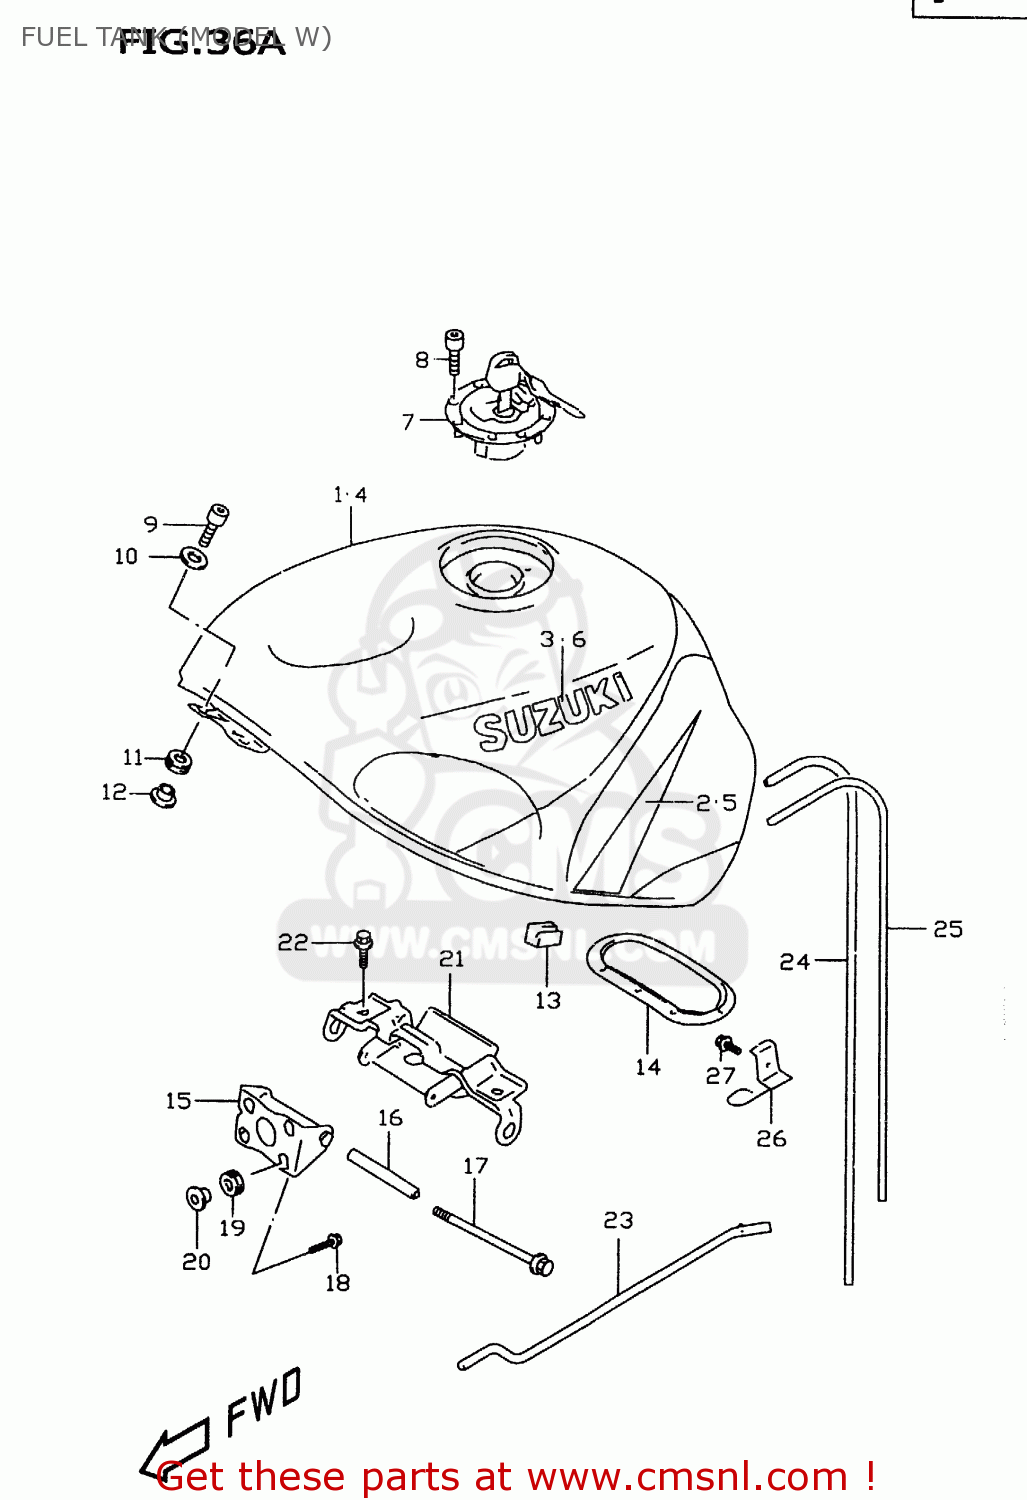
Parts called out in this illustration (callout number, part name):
1	TANK ASSEMBLY,FUEL
2	TAPE SET,FUEL TANK
3	EMBLEM,FUEL TANK
4	TANK ASSEMBLY,FUEL
5	TAPE SET,FUEL TANK
6	EMBLEM,FUEL TANK
7	CAP SET,FUEL TANK
8	BOLT(5X20)
9	SCREW(6X25)
10	WASHER(6.5X18X1.6)
11	CUSHION
12	WASHER
13	CUSHION,FUEL TANK SIDE
14	PACKING,FUEL PUMP (NAS)
15	BRACKET COMP,FUEL TANK
16	SPACER,FUEL TANK RR
17	BOLT
18	BOLT 6X20,WITH PLAIN WASHER
19	CUSHION
20	WASHER
21	BRACKET,FUEL TANK NO.2
22	BOLT
23	STAY,FUEL TANK
24	HOSE(5X8.2X600)
25	HOSE(7X10.2X600)
26	GUIDE COMP,DRAIN HOSE
27	BOLT
